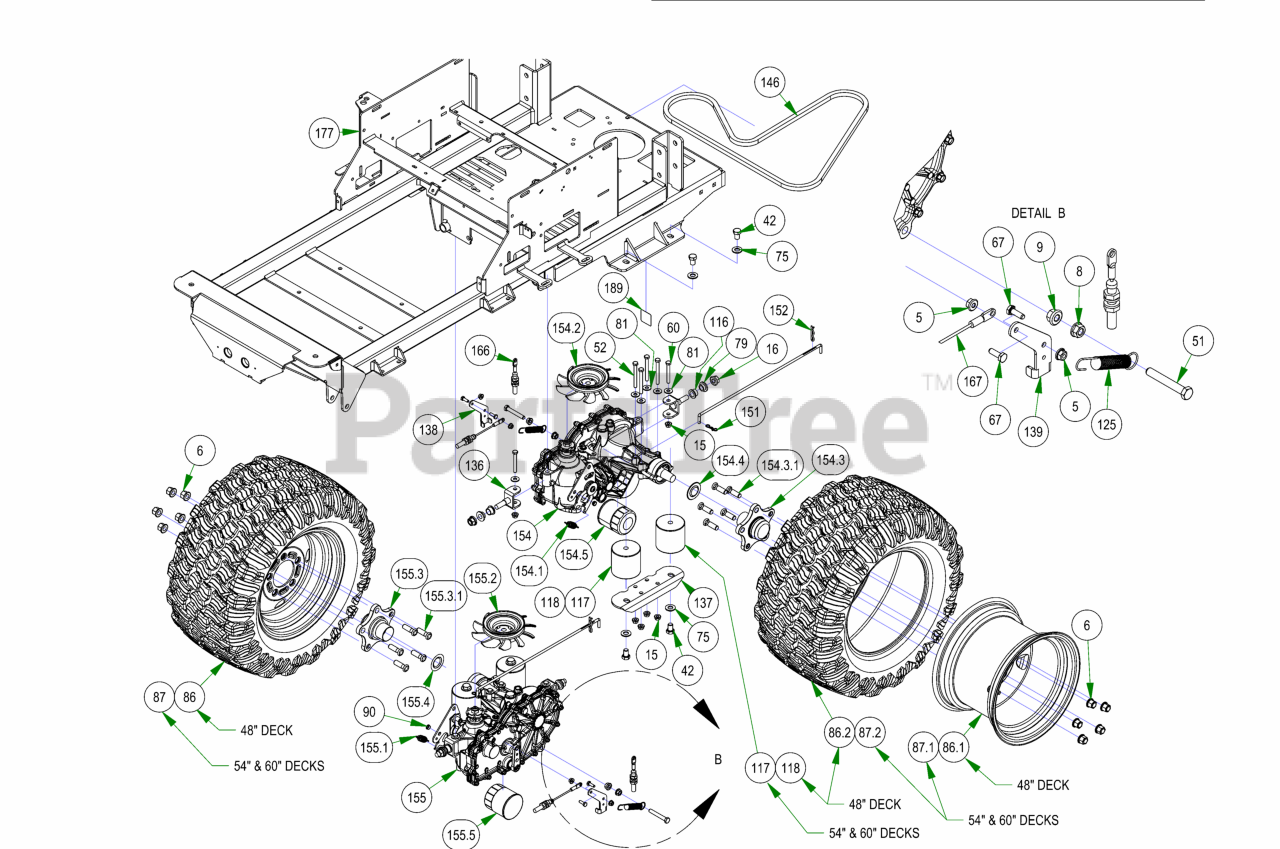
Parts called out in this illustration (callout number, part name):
5	1/4-20 NYL INSERT FLANGE LOCKNUT ZINC
6	Acorn Lug Nut
8	3/8-16 HEX SERRATED FLANGE NUT HARD/ZINC
9	3/8-16 NYLON INSERT FLANGE LOCKNUT (GR.F) ZINC
15	5/16-18 NYLON INSERT FLANGE LOCKNUT ZINC
16	1/2-13 NYLON INSERT FLANGE LOCKNUT ZINC
42	1/2-13 X 3/4 HEX CAP SCREW (GR.5) ZINC
51	3/8-16 X 2-1/2 HEX TAP BOLT (GR.5) ZINC Fully Threaded
52	5/16-18 X 3 HEX CAP SCREW (GR.5) ZINC
60	5/16-18 X 2-1/2 HEX CAP SCREW (GR.5) ZINC
67	1/4-20 X 3/4 HEX CAP SCREW (GR.5) ZINC
75	1/2 SAE FLAT WASHER (1-1/16" OD) GR.8 ZINC YELLOW
79	.525 ID SHOULDER WASHER NYLON
81	5/16 USS FLAT WASHER (7/8 OD) ZINC
86	23x9-12 Reaper Turf Tire & Wheel Assembly
86.1	12x7" Black Wheel
86.2	23x9-12 Reaper Turf Tire Only
87	23x11-12 Reaper Turf Assembly
87.1	12x8.5 Black Wheel
87.2	Tire, 23/11x12 Reaper Turf
90	Drive Arm Transaxle Spacer
103	Neutral Rod
116	.627 ID X .753 OD X .500 LGTH X 1.000 FLG OD X .094 FLG THICK FLANGED BEARING OIL-IMPREG BRNZ
117	Vibration Mount-Green Dot
118	Vibration Mount- Red Dot
125	Brake Return Spring
136	Maverick Rear Transaxle Pivot Bracket
137	Rear Suspension Transaxle Mount
138	Brake Arm Ext (Left)
139	Brake Arm Ext (Right)
146	75.8" Pump Belt
152	Neutral Rod Clip
154	2021 LH 3200 Transaxle
154.1	Gold Transaxle Spring
154.2	2021 ZT/Maverick Transaxle Fan/Pulley Kit
154.3	5 Bolt Hub Kit
154.3.1	Transaxle Wheel Studs/ Drum Brake Studs
154.4	2021 ZT/Maverick Transaxle Seat Kit (ZT-2800)
154.5	ZT Hydraulic Filter
155	2021 RH 3200 Transaxle
155.1	Gold Transaxle Spring
155.2	2021 ZT/Maverick Transaxle Fan/Pulley Kit
155.3	5 Bolt Hub Kit
155.3.1	Transaxle Wheel Studs/ Drum Brake Studs
155.4	2021 ZT/Maverick Transaxle Seat Kit (ZT-2800)
155.5	ZT Hydraulic Filter
166	2021 Load Balanced Brake Cable 1
167	2021 Load Balanced Brake Cable 2
177	2023 Maverick Frame - Painted
189	Patent Decal
